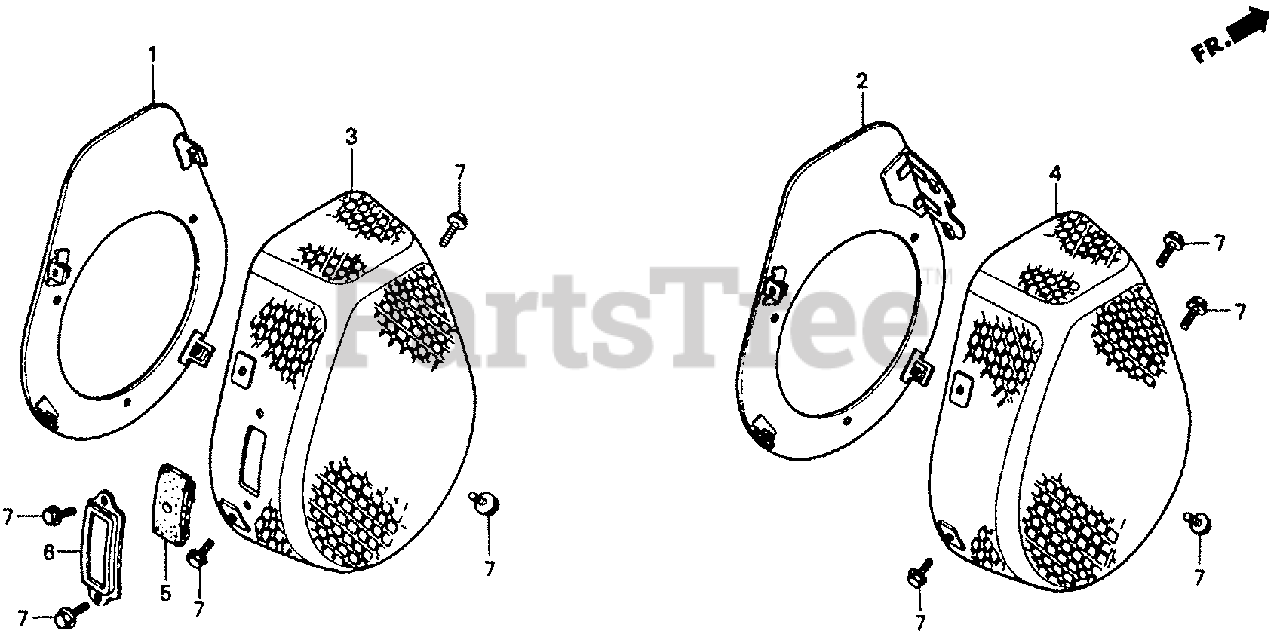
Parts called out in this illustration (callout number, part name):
1	BASE, DUST COVER
2	BASE, DUST COVER
3	COVER, DUST (NOT AVAILABLE)
4	COVER, DUST
5	GUIDE, ROPE
6	RIM, ROPE GUIDE
7	BOLT, FLANGE (6X10)
